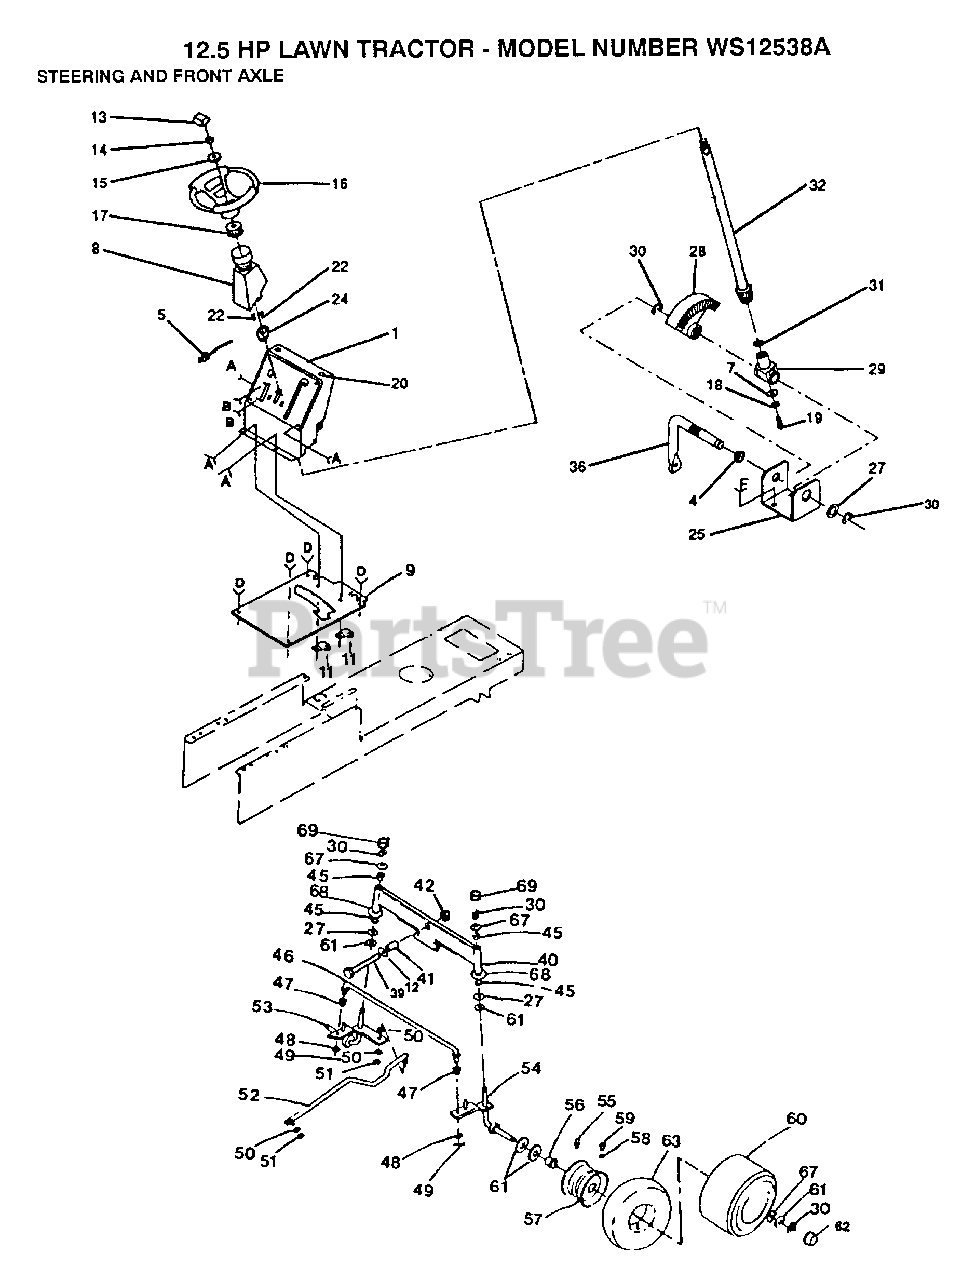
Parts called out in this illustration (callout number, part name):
4	NYLINER T
8	"TUBE, STR SHAFT"
11	CLIP T
13	INSERT-WHEEL LT
15	WASHER
17	ADAPTER LT
18	LOCKWASHER
19	"SCREW,SPECIAL"
24	"BUSHING,STEERING"
25	"BRKT,STEERING"
27	WASHER .T
29	SUPPORT.SHAFT
30	RING
31	THRUST WASHER
32	SHAFT WELD STR T
39	BOLT LT
41	BEARING
45	COL. SRTG. BEAR.
48	WASHER
49	COTTER PIN
50	LOCKWASHER
53	SPINDLE-LH LT
55	FITTING LT
56	"FLANGE, BEARING"
58	VALVE CAP
59	VALVE STEM LT
61	WASHER
62	HUB CAP
63	TUBE.5.3/4.5/6
67	WASHER
68	WASHER
69	CAP
